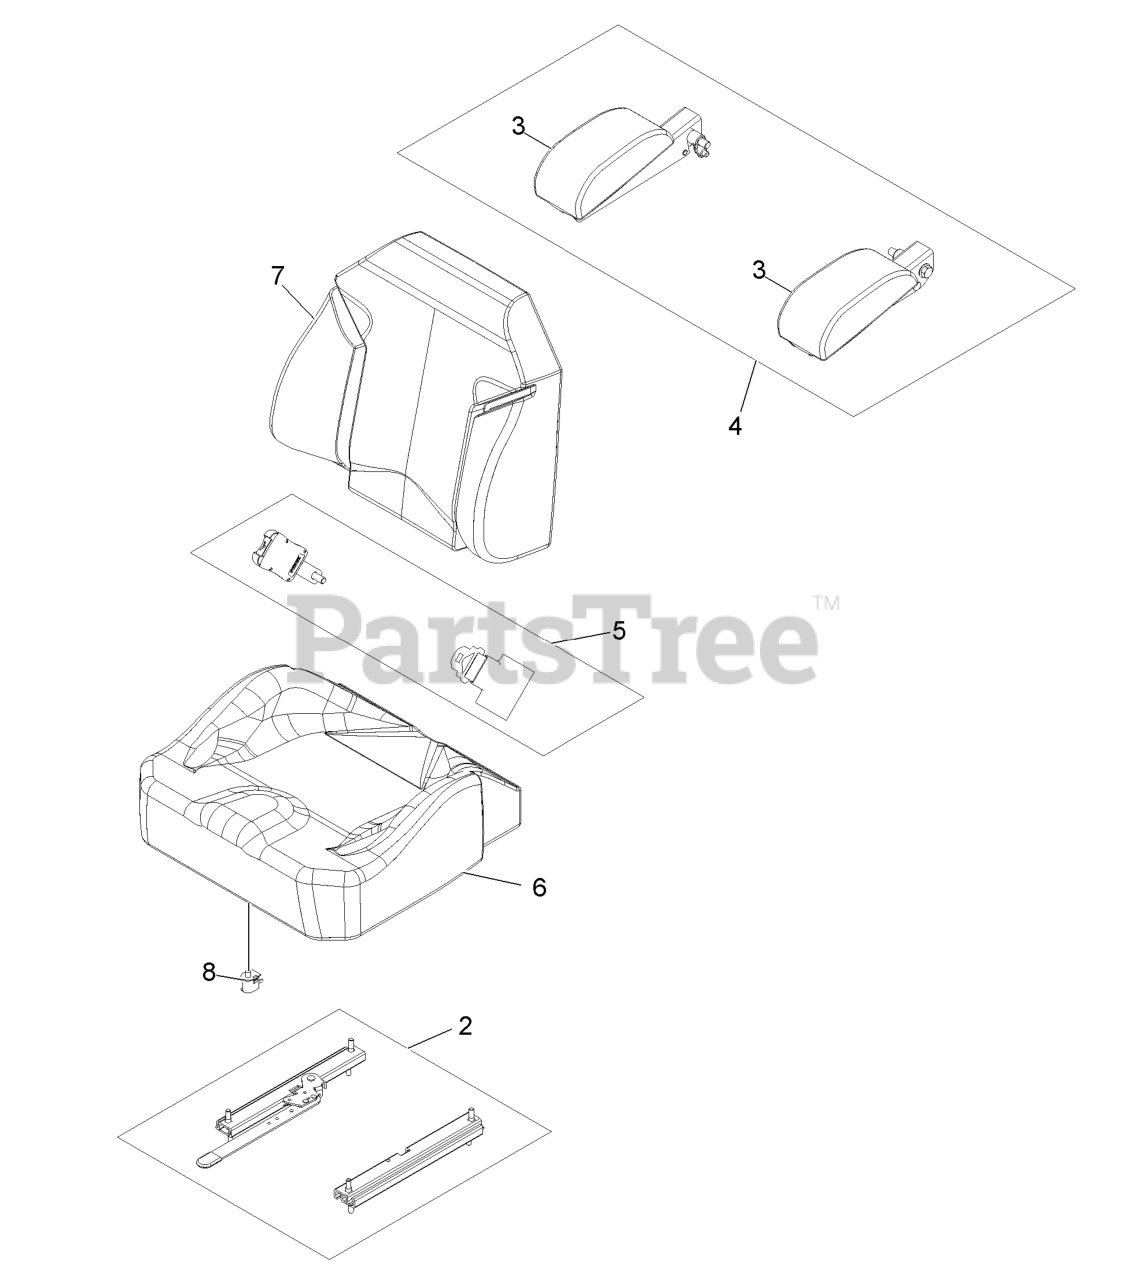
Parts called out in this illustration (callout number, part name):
2	SEAT TRACK SET
3	ARM REST PAD SET
4	ARM REST SET
5	SEAT BELT KIT
6	COVER,CUSHION
7	COVER,BACK
8	SWITCH-BAIL
